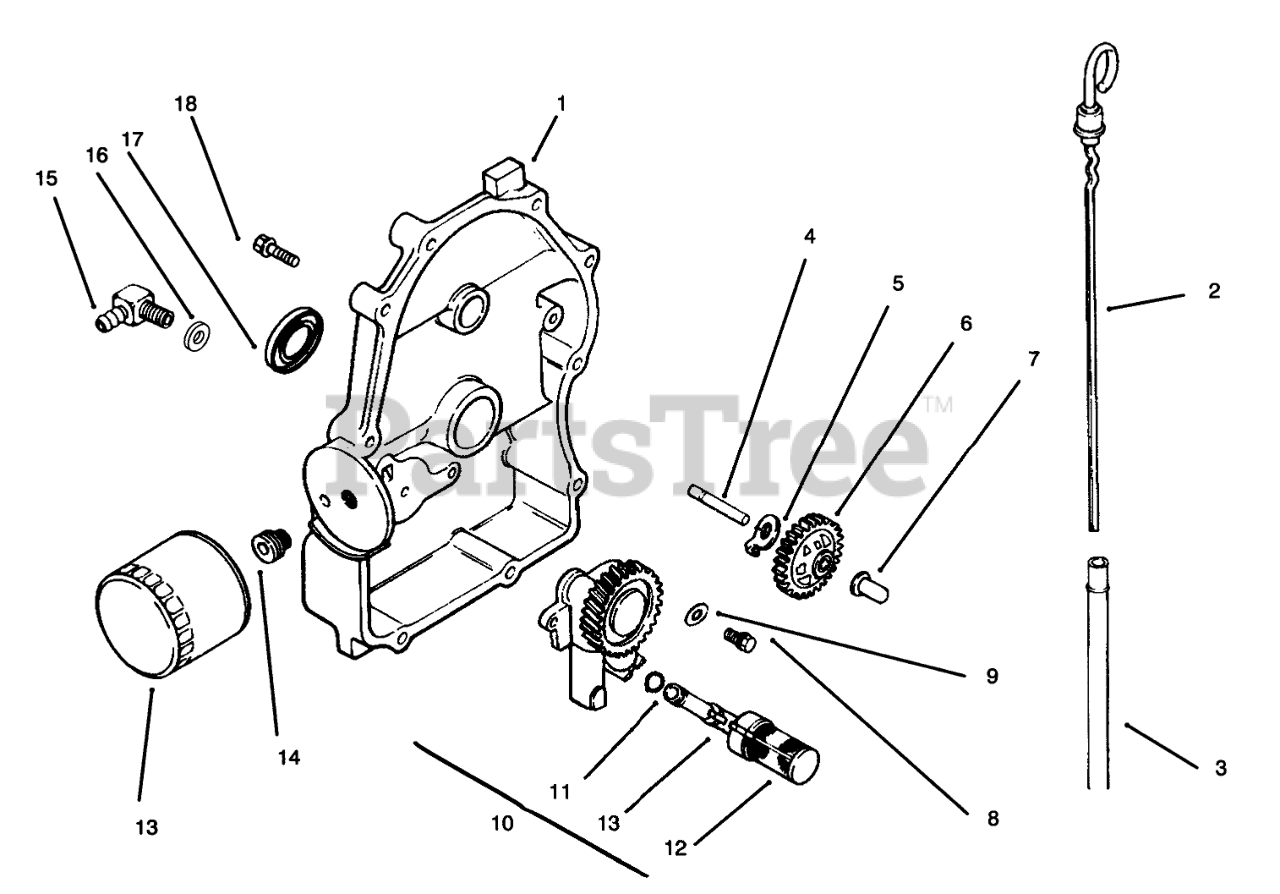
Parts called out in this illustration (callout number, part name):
1	Plate-Closure (Incl. Ref.# 2-7, 10-12, 16 & 17)
2	Dipstick
3	Tube-Dipstick
4	Shaft-Govenor Gear
5	Tab-Locking
6	Kit-Governor Gear Assembly (Incl. Ref. #7)
7	Pin-Governor
8	Screw
9	Washer
10	Oil Pump Assembly (Incl. Ref. #11-12)
11	"O"Ring
12	Pick-up, Oil
13	Filter-Oil
14	Nipple-Oil Filter
15	Connector-90deg.
17	Seal-Oil
